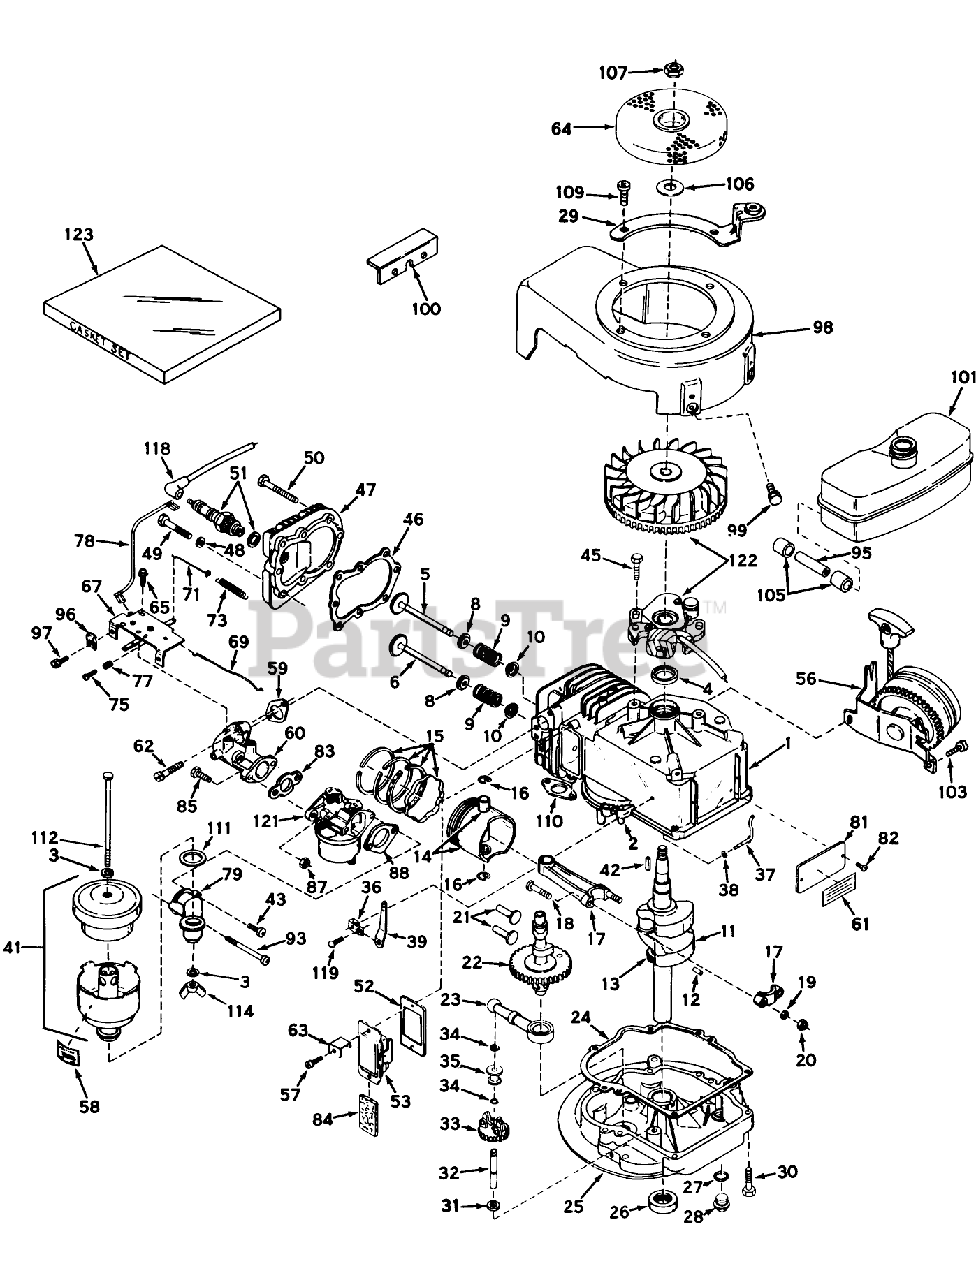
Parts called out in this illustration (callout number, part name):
1	Cylinder Assy. (Incl. Ref. 2 4)
2	Pin-Dowel
3	Washer Fibre
4	OIL SEAL
5	Valve, Intake (Incl. Ref. #38, 39 40) (Std.)
5	Valve, Intake(1/32"overs.)(Incl. Ref. 8, 9 10)
6	Valve, Exhaust (Standard)(Incl. Ref. 8, 9 10)
6	Valve, Exhaust (1/32" Overs.(Incl. Ref. 8, 9 10)
8	Cap-Upper Valve Spring
9	Spring-Valve
10	Cap-Valve, Spring
11	Crankshaft Assy. (Incl. Ref. 12 13)
12	Pin, Groove
13	Gear, Crankshaft
14	Piston Pin Assy. (Standard)(Incl. 2 of No. 16)
14	Piston Pin Assy. (.010 overs.)(Incl. 2 of Ref. 16)
14	Piston Pin Assy. (.020 overs.)(Incl. 2 of Ref. 16)
15	Ring Set, Piston (Std.)
15	Ring Set, Piston (.010 o.s.)
15	Ring Set, Piston (.020 o.s.)
16	Ring-Retaining, Piston Pin
17	Rod Assy., Connecting (Incl. Ref. #17)
18	Bolt, Connecting
19	Washer
20	LOCKNUT
21	Lifter-Valve
22	Camshaft
23	Oil Pump ASM
24	Gasket, Mounting
25	Flange Assy., Mounting (Incl. Ref. 26, 27, 28 32)
26	Seal Oil
27	Gasket-Oil Drain
28	Plug Oil Drain
29	Bracket Assy., Starter
30	Screw (1/4-20 x 1-1/4)
31	Washer-Flat
32	Shaft-Governor
33	Governor Gear ASM
34	Ring-Retaining
35	Spool-Governor
36	Clamp-Lever, Governor
37	Rod, Governor (Incl. No. 36)
38	Washer-Flat
39	Lever, Governor
41	Cleaner Assy., Air
42	Key Flywheel
43	KIT - SEAL WIPER
45	Screw
46	Gasket-Cylinder Head
47	CYLINDER HEAD
48	Washer
49	Screw
50	Screw
51	SPARK PLUG
52	Gasket Breather
53	Breather Assembly (Incl. Nos. 52 84)
56	Starter, Side Mount
57	Screw
58	Decal, Air Cleaner
59	Gasket, Intake
60	Pipe, Intake
61	480B GIL SNWTHWR O/
62	Screw, Fil. Hd. Sems
63	Retainer Clip
64	Screen, Flywheel
65	Screw (10-24 x 9/16)
67	Control Assy., Speed
69	Link, Throttle to Governor
71	Link, Governor Spring
73	Spring, Governor
75	Screw
77	Spring-Compression
78	Wire, Ground
79	Elbow, Air cleaner
81	IDENTIFICATION PLATE
82	Stud
83	Gasket
84	Element-Breather
87	Nut and Lock Washer (1/4-28)
88	Gasket
93	Screw
95	Line, Fuel
96	Conduit
97	Screw (10-32 x 3/8)
98	Housing, Blower
99	Screw (1/4-20x19/32)
100	Bracket, Shroud
101	Tank, Fuel
103	Screw, Fil. Hd. Sems
105	Line-Fuel (8.62)
106	Washer
107	Hex Nut
109	Screw
110	Gasket Exhaust
111	Gasket, Spacer
112	Bolt, Air Cleaner
114	Nut, Wing
118	Cover-Spark Plug
119	Screw
121	Carburetor
122	Magneto
123	Gasket Set
